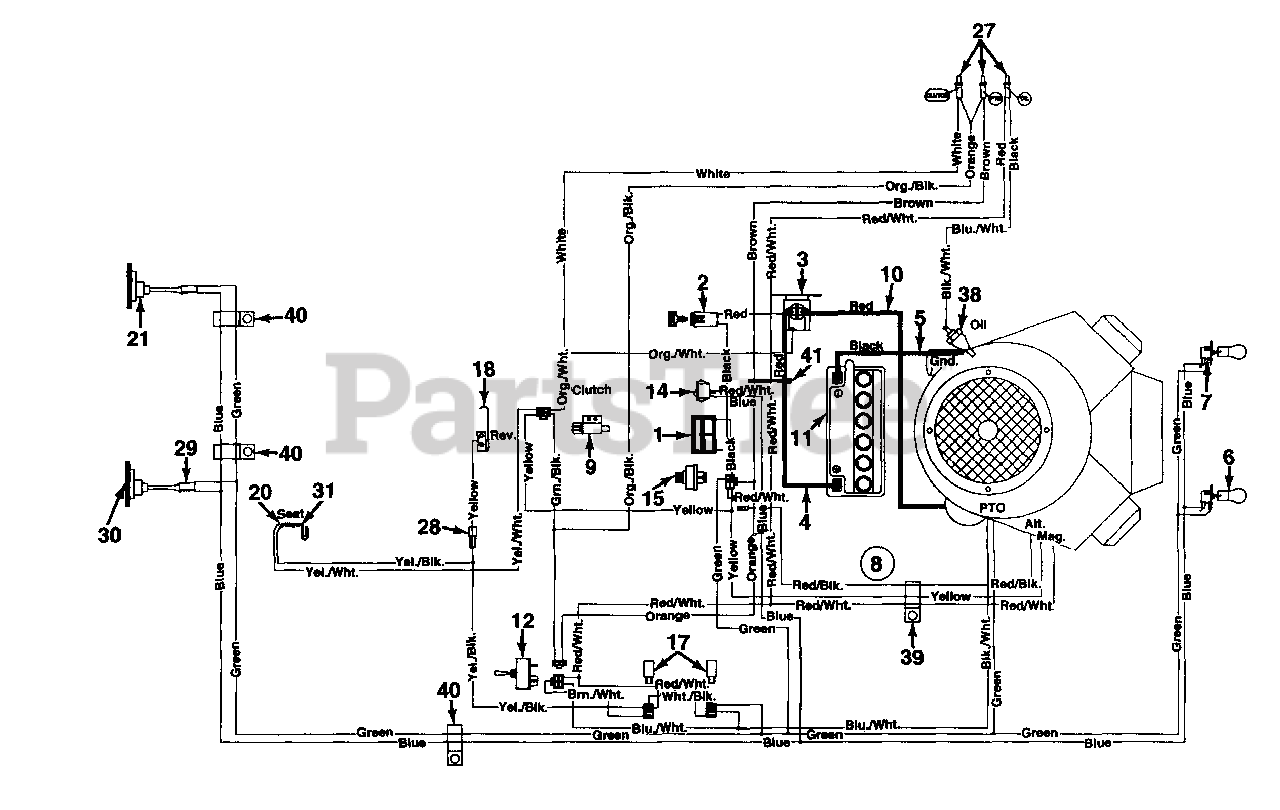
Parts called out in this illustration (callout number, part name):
1	Ammeter
2	Fuse 20 Amp
3	Solenoid
4	Wire
5	6 Ga. Red Wire 20" Lg.
6	Bulb
7	Socket
8	Wire Harness
9	Safety Switch
10	6 Ga. Black Wire
11	Battery
12	Switch
14	Light Switch
15	Ignition Switch
17	Relay
18	Spring Lever
20	Safety Switch
21	Tail light
27	Bulb
28	Transmission Ext. Wire
29	Tail light Harness
30	Bulb
31	Safety Switch
38	Oil Pressure Switch
39	Clamp 9/16" Dia.
40	Clamp 5/16" Dia.
41	Cable Tie
